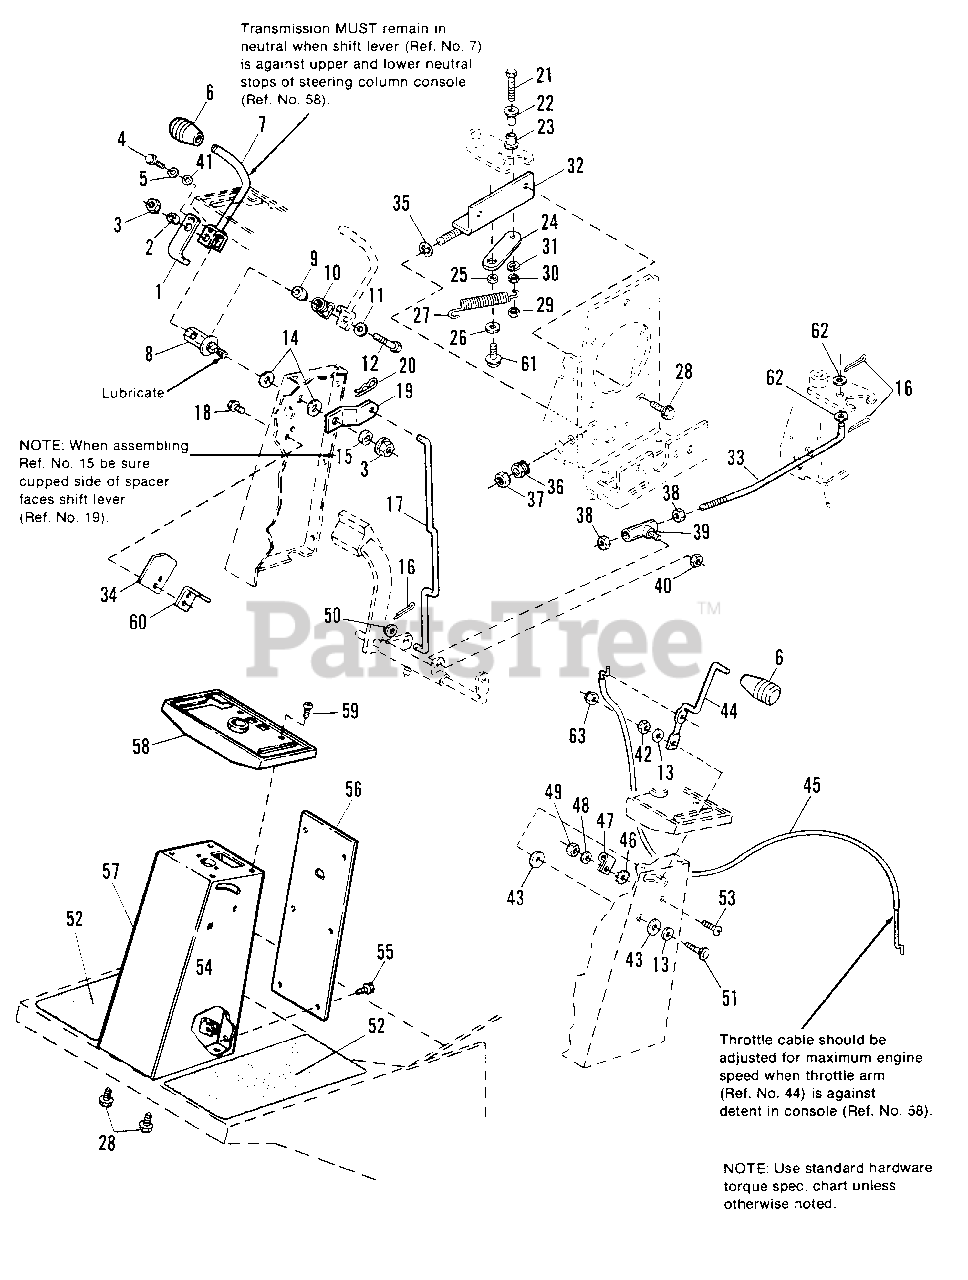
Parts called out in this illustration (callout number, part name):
1	NEUTRAL SWITCH ARM
3	NUT, Hex, ESNA, Lock, 5/16-18
4	SCREW, Taptite, #5-40 x 3/4
6	KNOB, Control
7	ROD ASSY., Shift
8	PIVOT, Shift (Incl. Ref. No. 15)
10	SPRING, Torsion
11	WASHER, Flat, 5/16
12	CAPSCREW, Hex, 5/16-18 x 1-3/4
13	WASHER, Flat, 1/4
14	WASHER, Nylon, 33/64 x 1
16	PIN, Cotter
17	ROD, Control, Vertical
18	SCREW, Taptite, #10-32 x 3/8
19	LEVER, Shift
20	PIN, Quick
21	CAPSCREW, Hex, 1/4-20 x 1-1/2
23	BUSHING, Nylon
24	ARM, Control
26	WASHER, Plain
27	SPRING, Extension
28	SCREW, Taptite, 5/16-18 x 1/2
29	NUT, Hex Centerlock, 1/4-20
30	NUT, Hex, 1/4-20
31	LOCKWASHER, 1/4
32	BRACKET ASSY., Control
33	ROD, Control
34	FLIPPER, Switch (Plastic)
36	NUT, Adjusting
37	NUT, Hex Jam, 3/8-24
38	NUT, Hex, 5/16-24
40	NUT, Hex Lock, 5/16-18
41	WASHER, Plain, #5
42	NUT, Hex, 1/4-20
43	WASHER, Nylon
44	THROTTLE ARM
45	CABLE, Throttle
46	LOCKWASHER, Ext. Tooth, #10
49	NUT, #10-32
50	WASHER, Plain
51	CAPSCREW, Hex, 1/4-20 x 1
53	SCREW, Rd. Hd., #10-32 x 1/2
54	SPEEDNUT, "U" Type
55	SCREW, Hex, Type AB
56	PANEL, Steering Column
57	STEERING COLUMN ASSY.
58	CONSOLE, Steering Column
59	SCREW, Taptite, 1/4-20 x 3/4
60	BRACKET, Switch
61	SCREW, Taptite, 5/16-18 x 5/8
62	WASHER, Plain
63	NUT, Hex Lock ESNA, 1/4-20
